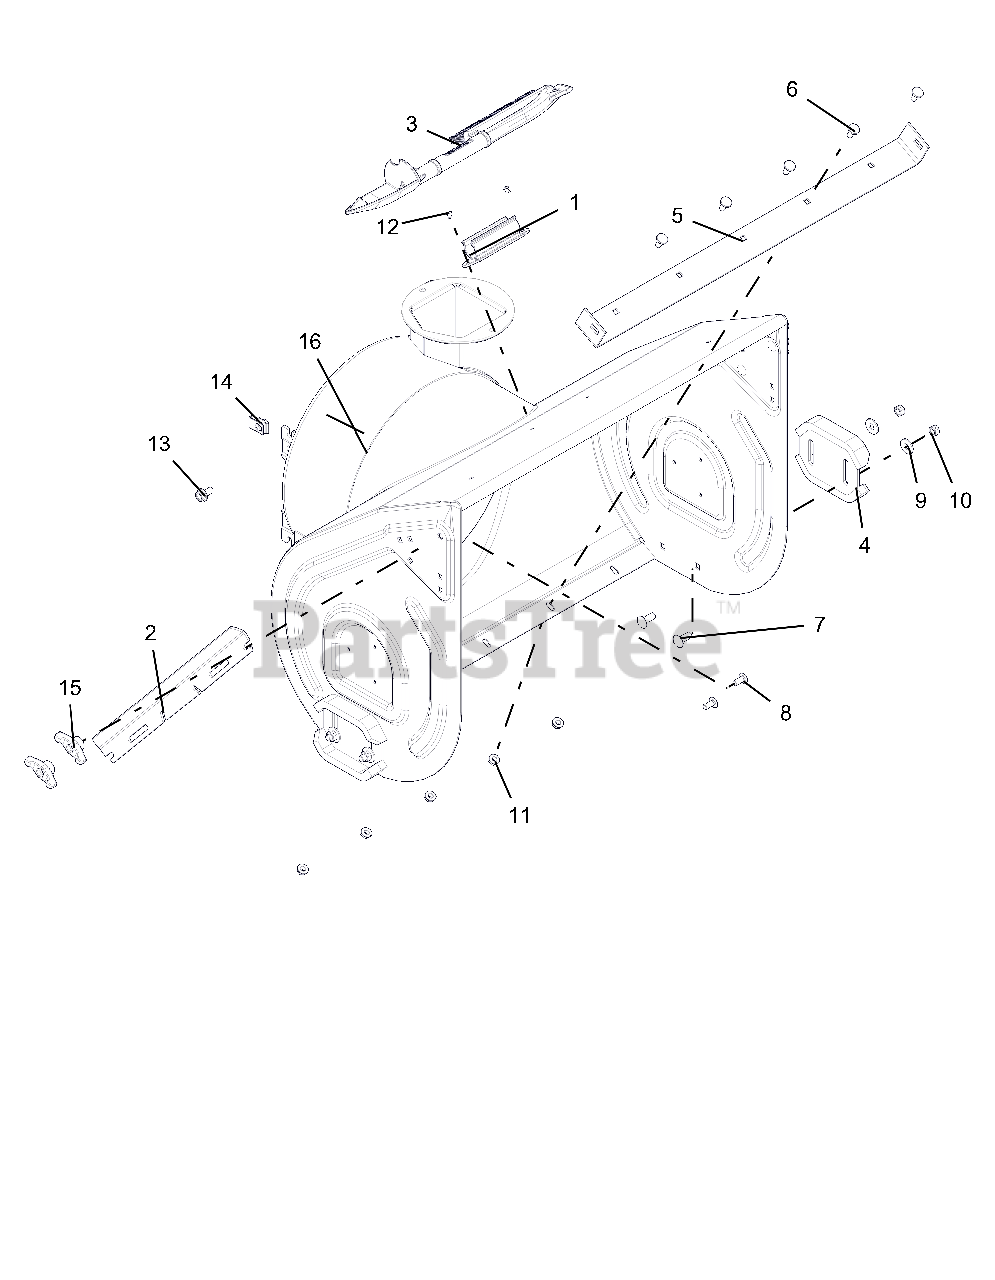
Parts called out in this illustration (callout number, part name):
1	MOUNT, SNOW CLEAN OUT
2	CUTTER, DRIFT
3	DEVICE, SNOW CLEAN OUT W/BRUSH
4	RUNNER, SKID SHOE
5	BLADE, SCRAPER-28"
6	BOLT, MODIFIED HEAD CARRIAGE
7	@BLT-RDHDSHSQNK.38-16X1.0 G5YZ
8	@BLT-RHDSSQNK .31-18X.75 G5YZ
9	@WSHR-FL-STL.438X1.00X.083 YWZ
10	@NUT-LK-CTR .38-16 YWZC
11	@NUT-LK-TOP-FLG .31-18 YWZC
12	RVT-POP .187 YZ
13	BLT-SERHFWH .38-16X.75 YWZC
14	NUT-RTNR .375-16X.37
15	KNOB,WING .31-18 UNC NYL/TALC
16	BLOWER HOUSING W/DECAL 28"
